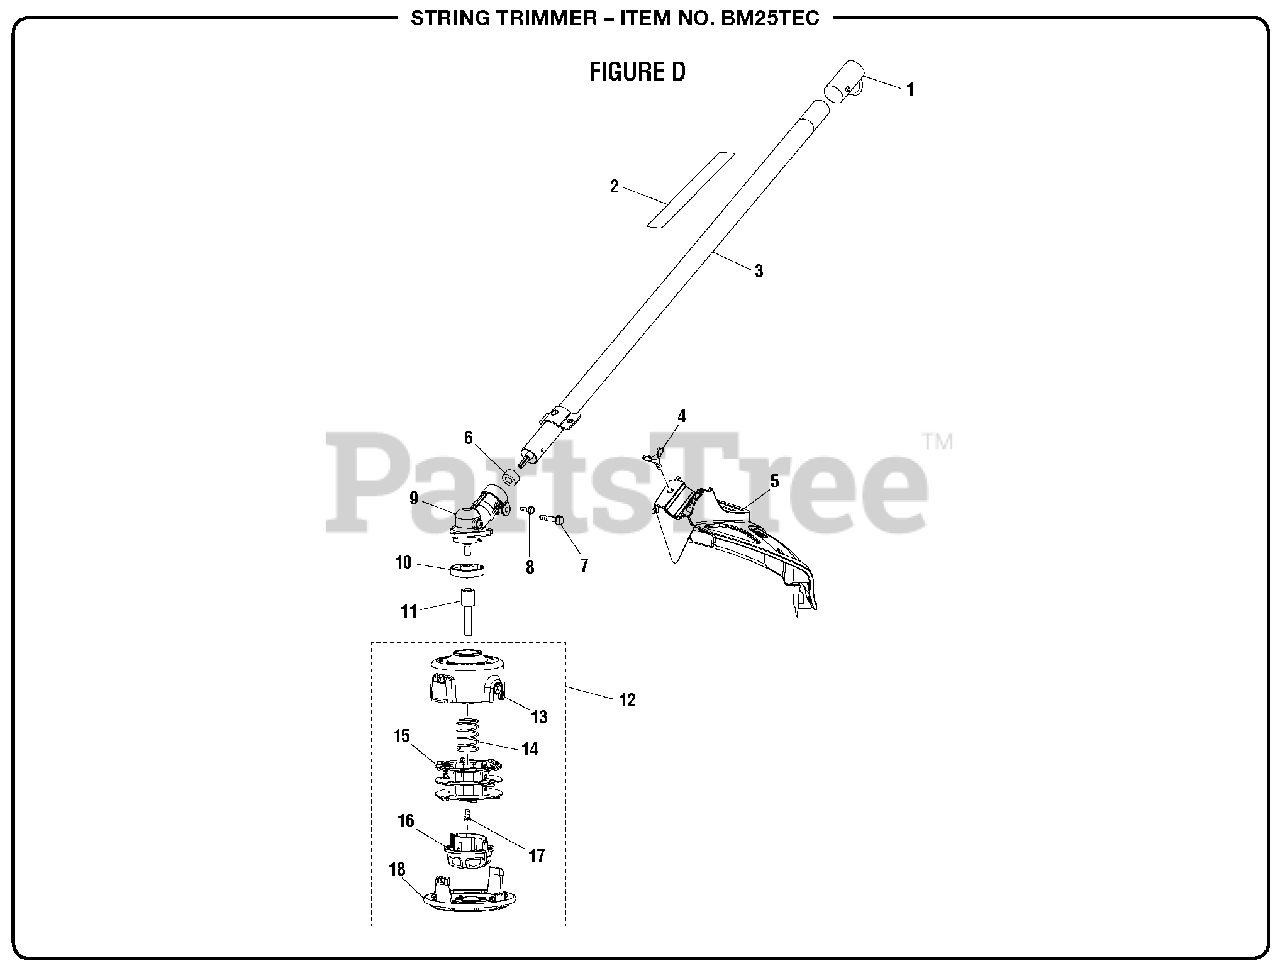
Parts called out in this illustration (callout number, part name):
1	Hanger Cap
2	Warning Label
3	Straight Shaft Assembly
4	Wing Screw (#1/4-20 x 1-1/4 in.)
5	Grass Deflector Assembly
7	Screw (1/4-20 x 1-1/4 in.)
8	Screw (#10-24 x 5/8 in. Hex Washer Hd.)
9	Gear Case Assembly
10	Flanged Washer
11	Trimmer Head Shaft Adaptor
12	Trimmer Head Assembly
13	Stringhead Housing
14	Compression Spring
15	Spool
16	Bump Knob
17	Bolt (5/16-18 x 1/2 in., L.H.)
18	Lower String Head Housing
